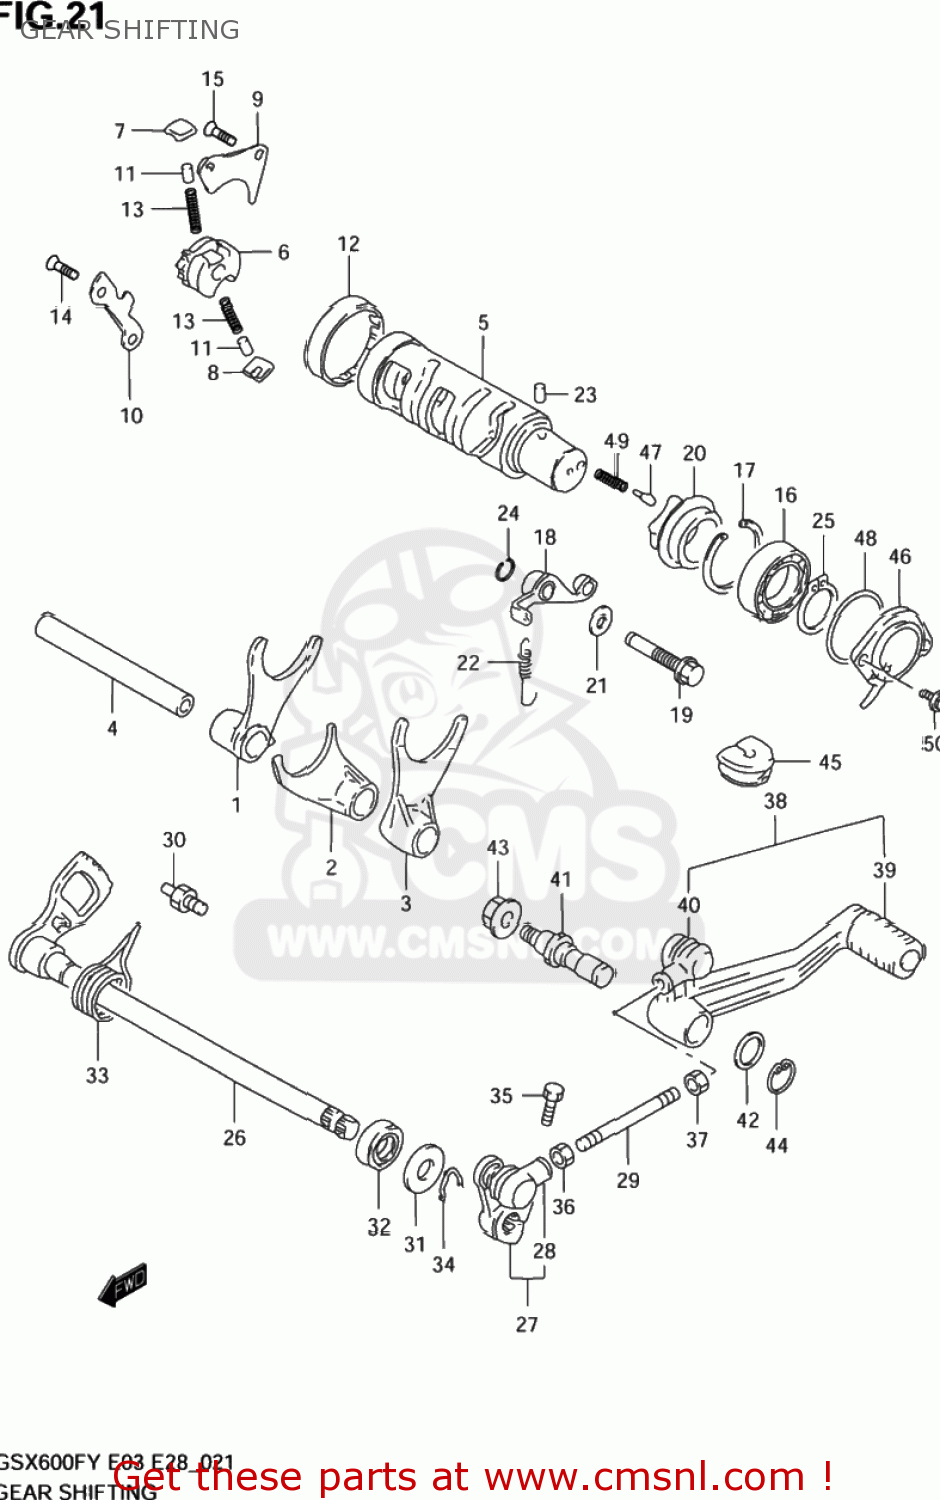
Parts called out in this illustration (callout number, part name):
1	FORK,GEAR SHIFT NO.1
2	FORK,GEAR SHIFT NO.2
3	FORK,GEAR SHIFT NO.3
4	SHAFT,GEAR SHIFT FORK(L:128)
5	CAM,GEAR SHIFT
6	GEAR,GEAR SHIFT CAM DRIVEN
7	PAWL,GEAR SHIFT NO.1
8	PAWL,GEAR SHIFT NO.2
9	LIFTER,GEAR SHIFT PAWL
10	GUIDE,GEAR SHIFT CAM
11	PIN(5X8)
12	BEARING(43X49X12)
13	SPRING
14	SCREW(6X12)
15	SCREW(6X12)
16	BEARING
17	CIRCLIP
18	STOPPER,GEAR SHIFT CAM
19	SHAFT,GEAR SHIFT CAM STOPPER
20	PLATE,STOPPER
21	GASKET(10X14X3.6) (NAS)
22	SPRING
23	PIN
24	CIRCLIP
25	CIRCLIP
26	SHAFT,GEAR SHIFT
27	ARM,GEAR SHIFT LINK
28	COVER,DUST
29	ROD,GEAR SHIFT LINK
30	STOPPER,GEAR SHIFT CAM
31	WASHER (12.5X26X1.6)
32	OIL SEAL
33	SPRING
34	CIRCLIP,12 MM
35	BOLT
36	NUT
37	NUT
38	LEVER ASSY,GEAR SHIFT
39	RUBBER,GEAR SHIFT PEDAL
40	COVER,DUST
41	SHAFT,GEAR SHIFT LEVER
42	WASHER(12.5X20X1)
43	NUT
44	CIRCLIP,12 MM
45	GROMMET,LEADWIRE
46	BASE ASSY,GEAR SHIFT TERMINAL
47	PIN(5X15.5)
48	O RING(D:2.4,ID:35.5)
49	SPRING
50	SCREW
